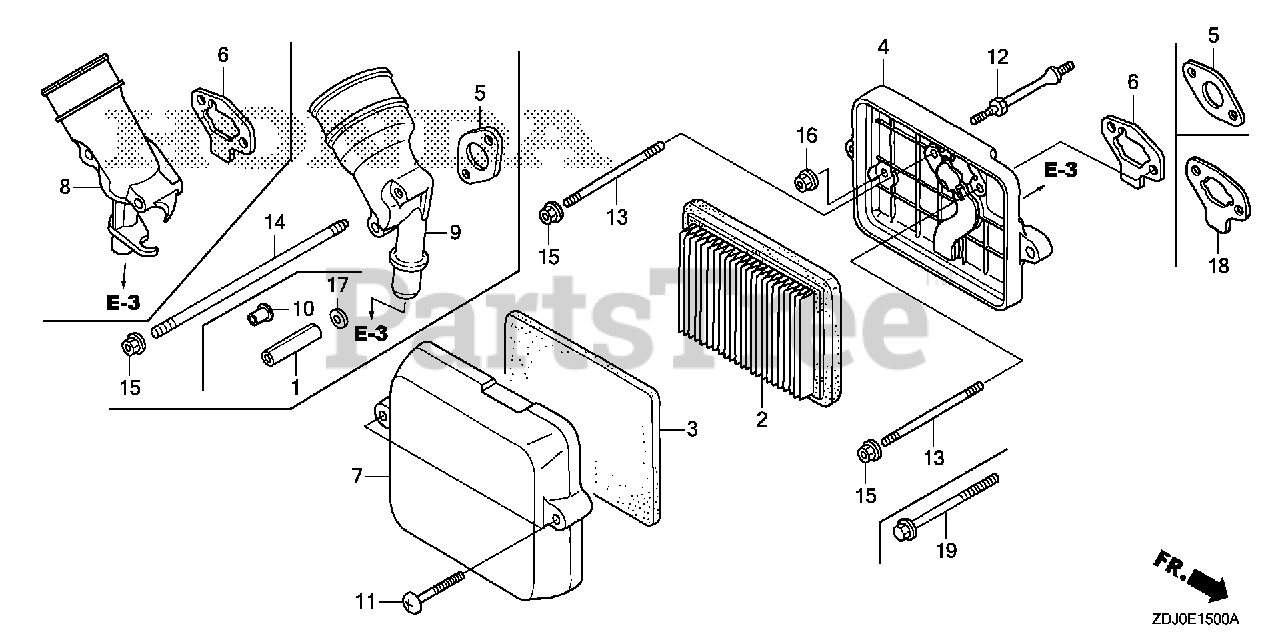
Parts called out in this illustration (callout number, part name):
2	ELEMENT, AIR CLEANER (TOYO ROKI) (ENGINE NO.)
4	HOUSING, AIR CLEANER
5	GASKET, AIR CLEANER
7	COVER, AIR CLEANER
11	BOLT, AIR CLEANER COVER
12	BOLT, STUD
13	BOLT, STUD (5X85)
15	NUT, FLANGE (5MM)
16	NUT, FLANGE (6MM)
